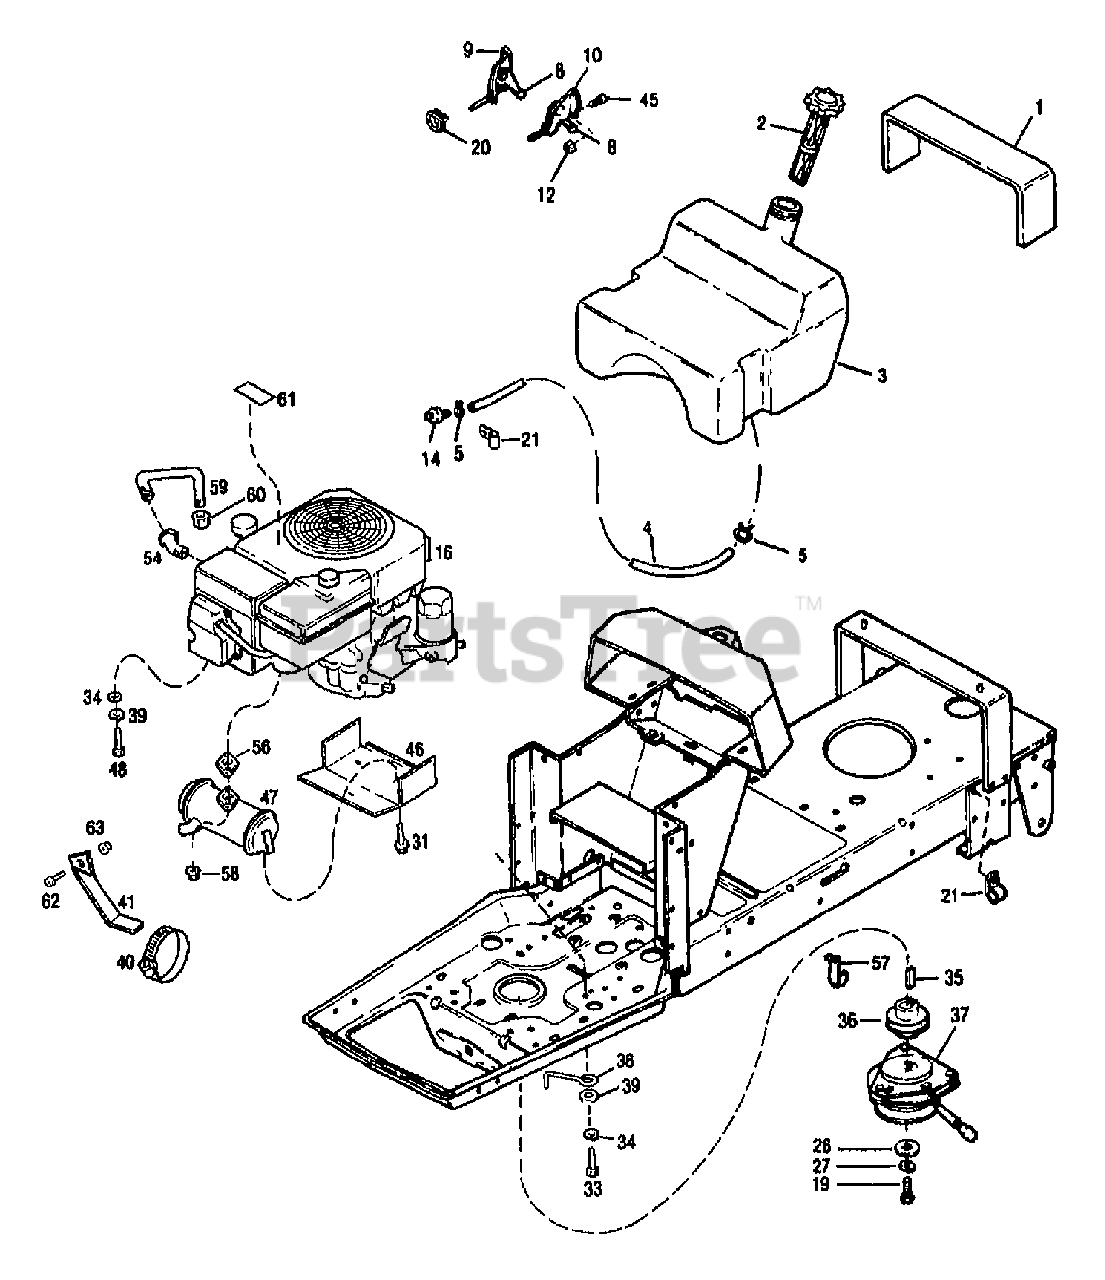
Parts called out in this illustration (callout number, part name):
1	PAD-FUEL TANK
2	CAP-GAS
3	TANK-FUEL
4	LINE-FUEL 52"
5	CLAMP-HOSE
8	KNOB
9	THROTTLE-CONTROL
10	C-CONTROL
12	NUT W/LKWASHER 10-24 ZP
14	FILTER-FUEL
16	ENGINE, KOHLER MODEL CV1259 (OHV) 12.5 HP
19	SCR-HH M10X1.5X80
20	TIE-CABLE NYLON BLACK
21	CLIP-J
26	WASHER-SPEC 1.42X.468X.25 ZP
27	WASHER-LK .438 ZP
31	SCR-HFLK 1/4-20 X .375
33	SCR-HH M8-35
34	WASHER-LK .312 ZP
35	KEY-.25 SQ X 2.5
36	SHEAVE
37	CLUTCH-ELECTRIC
38	CLUTCH-RETAINER
39	WASHER-FLAT 5/16 SAE
40	CLAMP-WORM
41	BRKT-MUFFLER
46	SHIELD-HEAT
47	KIT-MUFFLER
48	BOLT-M8X25
54	ELBOW-45 DEGREES
56	GASKET
57	HANGER-CABLE
58	NUT
59	TUBE-OIL DRAIN
60	CAP-DRAIN TUBE
61	DECAL-ENGINE
62	SCR-HH 1/4-20X.625
63	NUT-HF/LK 1/4-20 ZP
